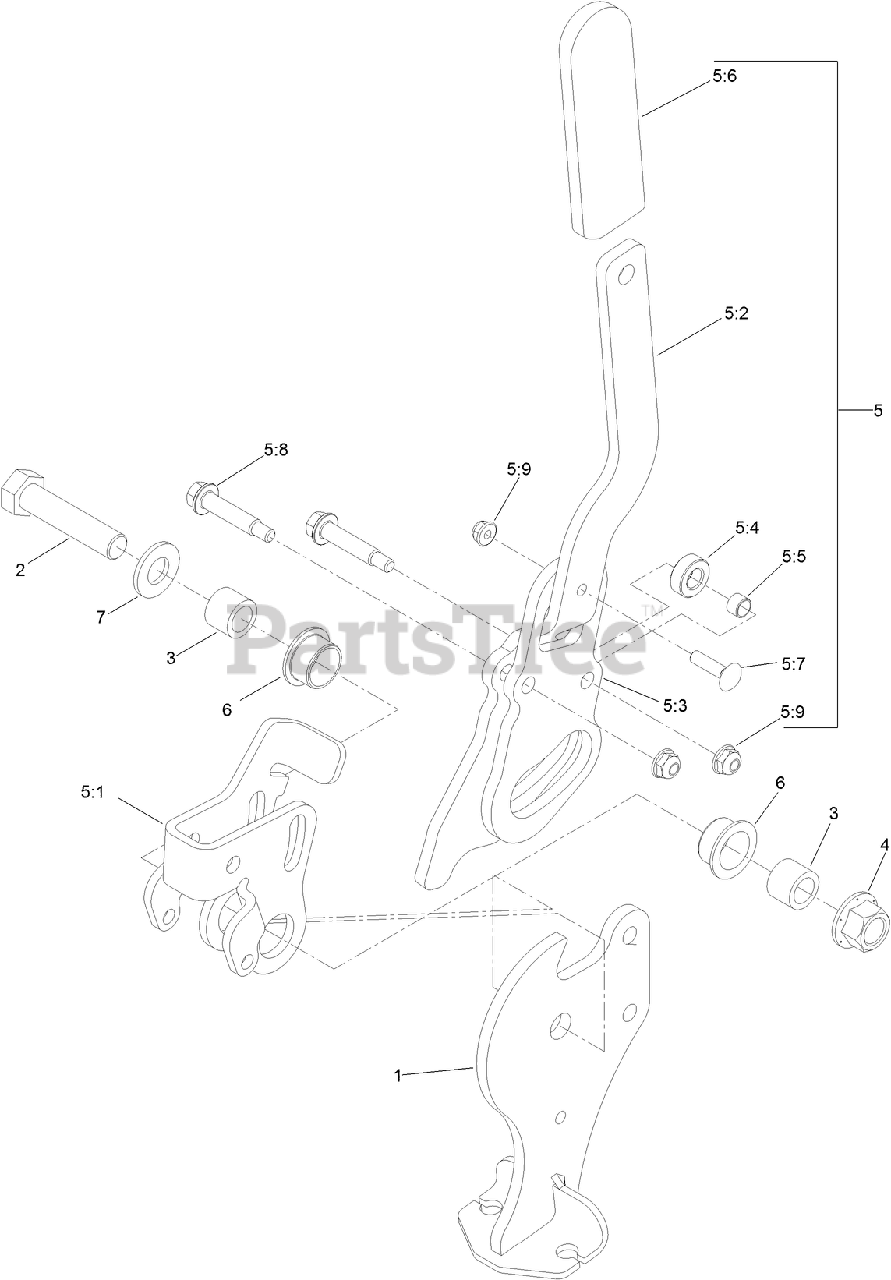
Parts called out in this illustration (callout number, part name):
1	PIVOT-BRAKE
2	SCREW-HH
3	SPACER
4	NUT-LOCK
5	HANDLE ASM
5:1	BELLCRANK-BRAKE
5:2	HANDLE-BRAKE
5:3	PLATE-HANDLE
5:4	ROLLER-BRAKE
5:5	BEARING-SLEEVE
5:6	GRIP-LEVER
5:7	SCREW-CARR
5:8	SCREW-SHOULDER
5:9	NUT-HF
6	BUSHING-FLANGE
7	WASHER-FLAT
